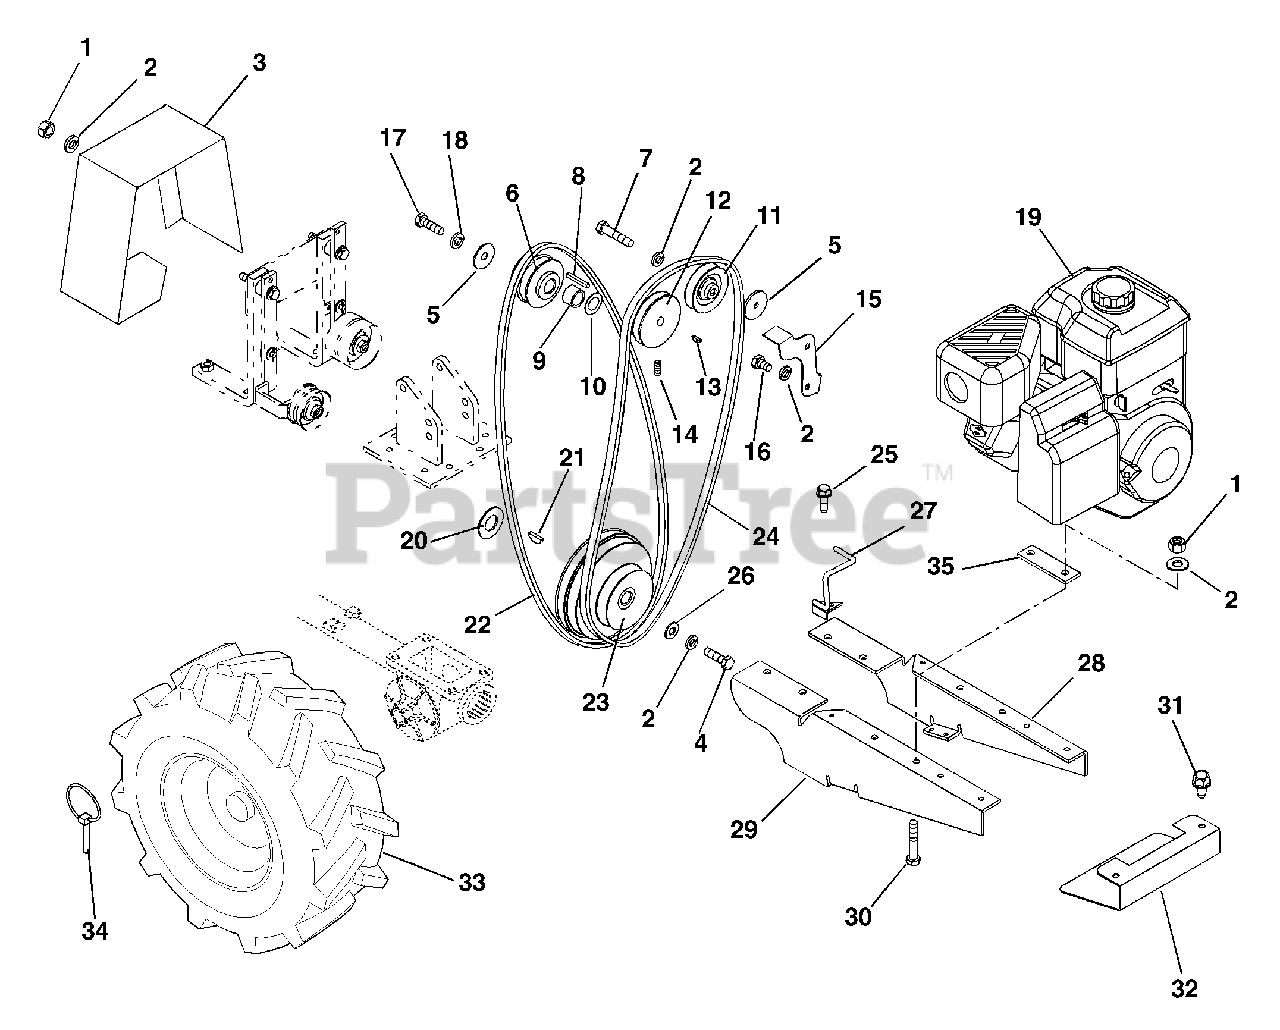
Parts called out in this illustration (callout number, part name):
1	@NUT-HEX .31-18 YWZC
2	@WSHR-LK .31X.078 REG YWZC
3	COVER, BELT W/DECALS
4	@BLT-HEX .31-18X1.00 GR5 YWZC
5	@WSHR-FL-STL.38X.875X.083 YWZC
6	SHEAVE, FORWARD
7	BLT-HEX .31-24X1.50 GR5 YWZC
8	KEY-SQ .188X1.5X.187 SAE 8630
9	SPACER .765X.875X.750
10	WSHR-HDND-THRST .758X1.23X.031
11	IDLER-V 2.625X.312
12	SHEAVE REVERSE OHH50
13	KEY-WDRF .125X.625X.250 SAE5
14	SCR-SET .25-20X.25 SKHCUPDL
15	BELT FINGER
16	SCR-CAP .31-24X.50HH GR5 YWZC
17	BLT-HEX .31-24X1.00 GR5 YWZC
18	@WSHR-LK .31X.078 REG YWZC
19	ENGINE, 7.0 HP B&S INTEK OHV
20	WSHR-FL-STL .699X1.375X.059
21	KEY-WDRF .188X.75X.313 SAE 9
22	V-BELT, 4L-WRAPPED
23	SHEAVE - TRANSMISSION
24	V-BELT, 3L-WRAPPED
25	SCR-TAP .25-20X.75 HWH TR YWZ
26	WSHR-FL-STL .328X.87X.179 YWZC
27	FINGER, BELT SER 18"
28	L H ENGINE MTG BRKT
29	R H ENGINE MTG BRKT
30	@BLT-HEX .31-18X2.50 GR5 YWZC
31	@SCR-TAP .31-18X.50 HWH TR YWZ
32	COVER, ENGINE BRKT
33	T/WHL ASSY RH
34	PIN-LOK .31X2.00
